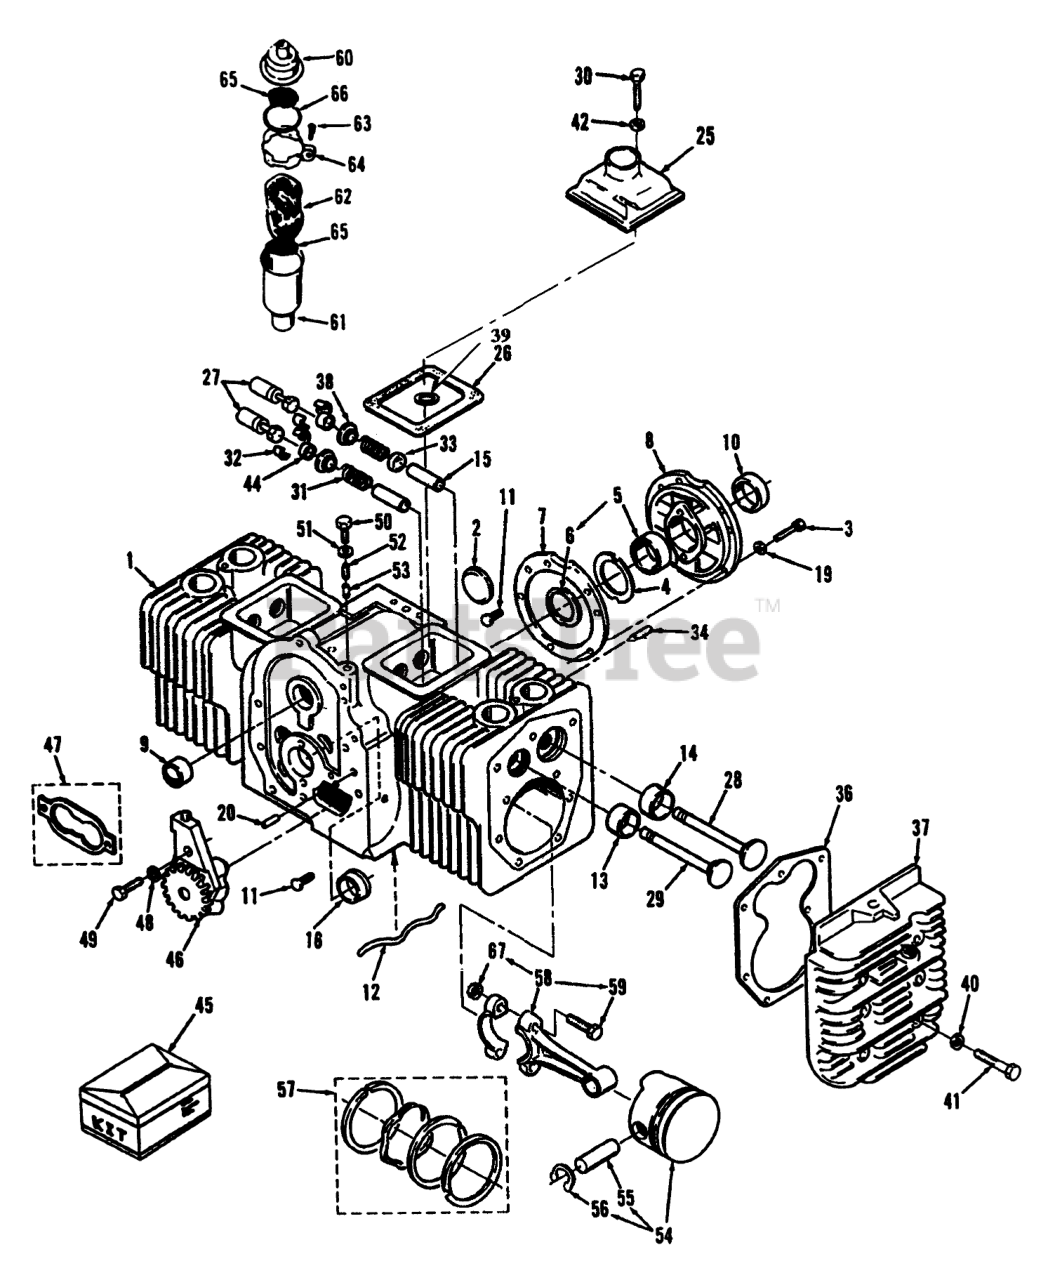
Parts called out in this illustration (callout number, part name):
1	CYLINDER BLOCK
2	Plug
3	Bolt 3/8-16x 1-1/4
5	Bearing-Crankshaft, Rear (Includes Thrust Washer) 57-8050 Standard
6	Thrust Washer
7	GASKET
8	PLATE-BEARING, REAR
9	Camshaft Brg
10	Oil Seal
11	Screw
12	Oil Tube
13	Insert-Valve Seat, Exhaust
14	Insert-Valve Seat, Intake
15	Guide-ExhaustValve
16	Bearing-Crankshaft, Front, Flanged
19	Washer
20	Pin
25	Cover-Valve
26	GASKET
27	Tappet-Valve
28	Intake Valve
29	Exhaust Valve
30	HHCS 1/4-20 X 1 3/4
31	Spring
32	VALVE SPRING LOCK
33	Seal
34	Screw
36	Gasket
37	HOUSING CYL RH
38	Washer
39	Washer
40	Washer
41	Bolt
42	Washer
44	VALVE CAP
45	Kit-Gasket
46	Oil Pump
47	GASKET KIT
48	Washer
49	SCREW - CAP HEX HEAD
50	Bolt
51	Washer
52	Spring
53	Piunger
54	Piston (Includes Pin & Retaining Rings) 92-0901 Standard
55	Pin-Piston
56	Retaining Ring
57	Kit-Ring, Piston 92-0905 Standard
58	Rod-Connecting (Includes Bolt & Nut)
59	Rod Bolt
60	BREATHER-CAP AND VALVE
61	TUBE-BREATHER
62	FILTER
63	SCREW-TAPPING, ROUND HEAD
64	Clamp
65	SCREEN-BREATHER TUBE
66	SEAL - O-RING
67	Nut
